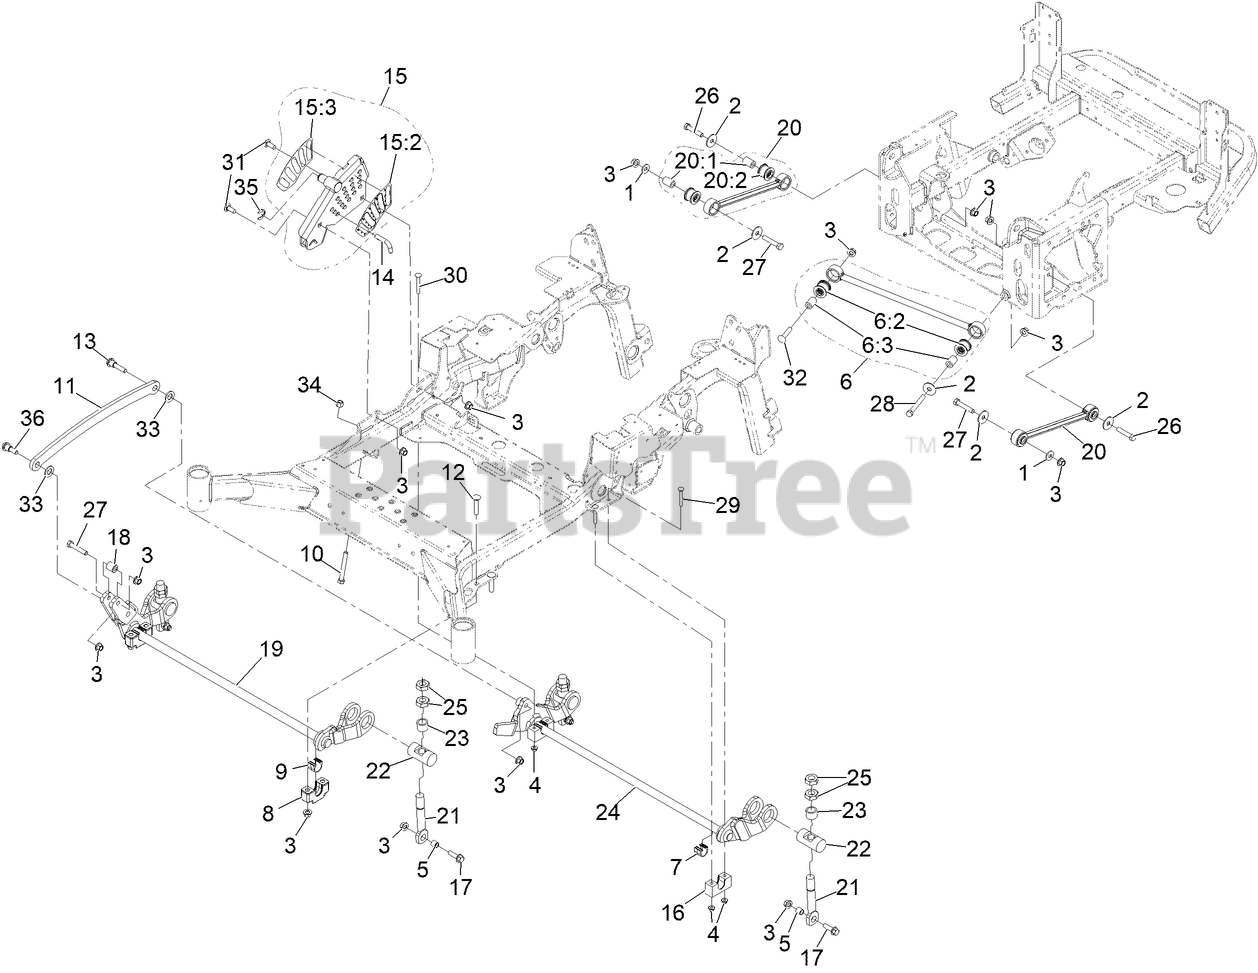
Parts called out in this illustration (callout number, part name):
1	WASHER-SPRING
2	WASHER-THRUST
3	NUT-LOCK
4	NUT-HF, NI
5	SPACER-PLAIN
6	PANHARD ROD ASM
6:2	BUSHING-SUSPENSION, RUBBER
6:3	SPACER
7	BEARING-CROSS SHAFT, REAR
8	SUPPORT-CROSS SHAFT, BEARING
9	BEARING-CROSS SHAFT, FRONT
10	BOLT-TAP
11	LINK-LIFT, DECK
12	BOLT-CARR
13	SCREW-HHF, SHOULDER
14	PIN-HOC
15	HOC ASM
15:2	DECAL-HEIGHT OF CUT
15:3	DECAL-HEIGHT OF CUT, OUTER
16	SUPPORT-CROSS SHAFT
17	SCREW-HHF
18	SPACER-PIVOT
19	DECKLIFT-FRONT, 144 [BLACK]
20	DECK STRUT ASM 85A
20:1	SPACER
20:2	BUSHING-RUBBER
21	LINK, DECK LIFT ADJUSTER
22	TRUNNION, DECK LIFT
23	SPACER, DECK LINK
24	WLD, DECK LIFT-REAR
25	NUT-HEX
26	SCREW-HH
27	SCREW-HH
28	SCREW-HH
29	SCREW-CARR
30	SCREW-CARR
31	SCREW-CARR, SHORT NECK
32	SCREW-CARR
33	WASHER-FLAT
34	NUT-LOCK, NI
35	RING-RETAINING
36	SCREW-SHOULDER, HHF
